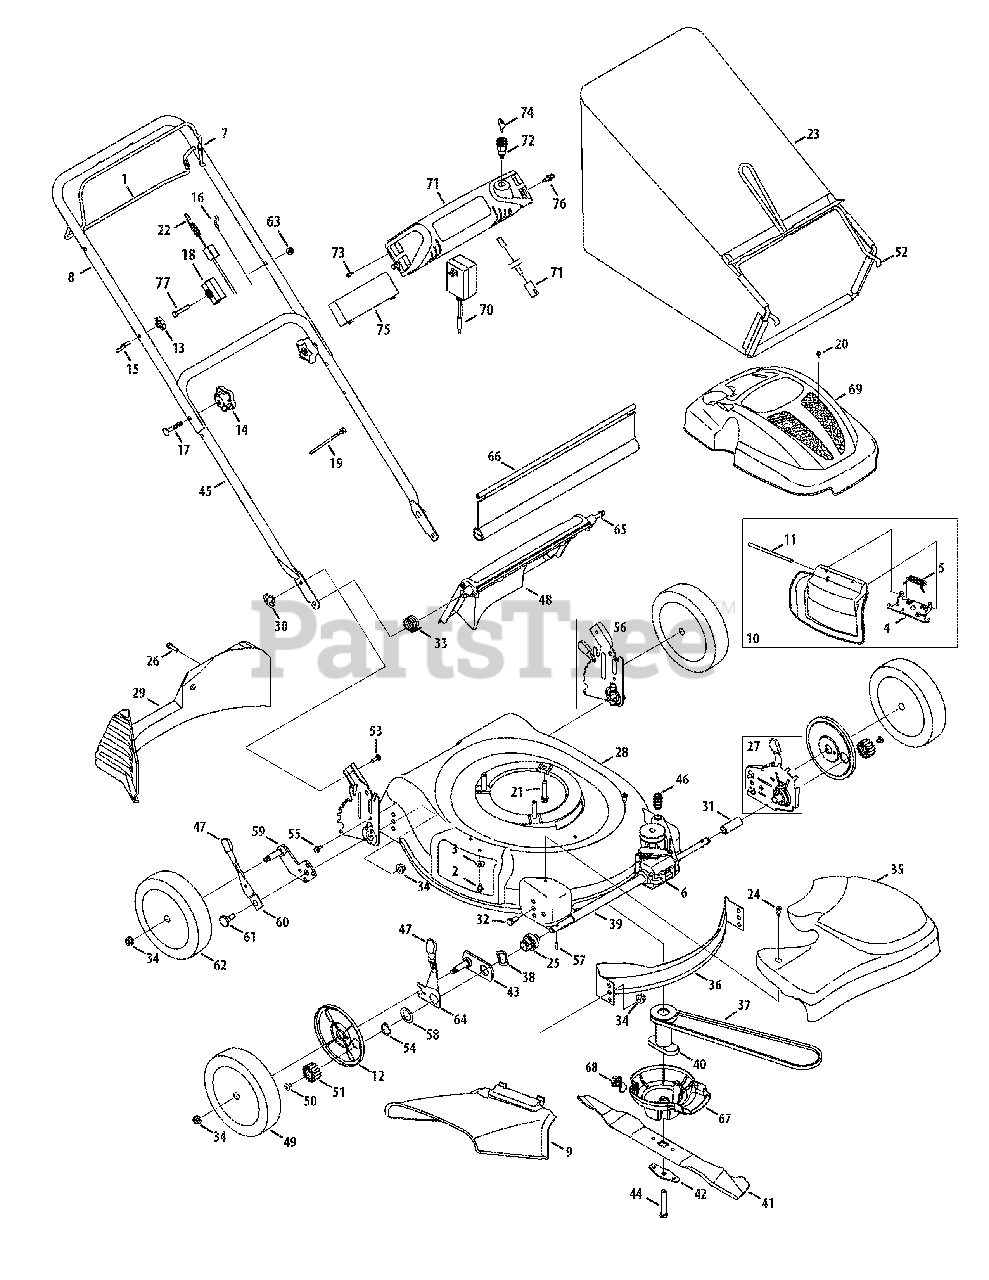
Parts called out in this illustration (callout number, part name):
1	Drive Control
2	TT Screw 1/4-20 x 0.5
3	Bell Washer.265 x 0.75
4	Deflector Chute Adapter
5	Torsion Spring
6	Transmission Assembly
7	Blade Control
8	Upper Handle
9	Chute Deflector
10	Mulch Plug Complete
11	Hinge Pin
12	Wheel Dust Cap
13	Handle Knob
14	Star Knob
15	Eye Bolt
16	Control Cable
17	Carriage Bolt 5/16-18 x 2.0
18	Control Cable Mount
19	Cable Tie
20	Screw, HL, #12-16 x 1.00
21	Self-Tapping Sems Screw
22	Drive Cable
23	Grass bag
24	Shoulder Screw # 12 -24
25	Front Bearing Assembly
26	Screw, 1/4-15 x 1.000
27	Height Adjustment Ass’y - RH
27	Height Adjustment Ass’y - LH
29	Rear Baffle
30	Wing Nut
31	Slev. Spacer 1.4" Lg.
32	Hex Screw, 3/8-16 x.75
33	Torsion Spring - RH
34	Flange Lock Nut, 3/8-16
35	Transmission Cover
36	Front Baffle
37	V-Belt
38	Wave Washer
39	Sleeve Spacer 8.985" Lg.
40	One Piece Blade Adapter
41	21" Mulching Blade
42	Blade Bell Support
43	Pivot Plate Assembly
44	Hex Screw 3/8-24 x 2.50
45	Lower Handle
46	Belt Tension Spring
47	Adjustment Knob
48	Rear Discharge Door
49	Front Wheel
50	Screw, 1/4-20 x .390
51	Gear 14T RH FWD
51	Gear 14T LH FWD
53	Carriage Bolt 1/4-20
54	Snap Ring
55	TT Scr. w/Washer 1/4-20 x.625
56	Handle Bracket Assembly - RH
56	Handle Bracket Assembly - LH
57	Dowel Pin
58	Washer
59	Pivot Arm Assembly - RH
59	Pivot Arm Assembly - LH
60	Rear Spring Lever
61	Shoulder Scr.500 Dia. x.434
62	Rear Wheel
63	Nut, Flglk, 1/4-20
64	Front Lever - RH
64	Front Lever - LH
65	Pivot Rod
66	Rear Trailing Shield
67	Engine Baffle
68	Engine Baffle Bracket
69	Engine Shroud
70	Battery Charger
70	Battery Charger (w/LED Light)
71	Electric Start Harness Assembly
72	Key Switch
73	Screw, #10-16 x .750
75	Battery
76	Rivet
77	Screw, 1/4-20 x 1.50
